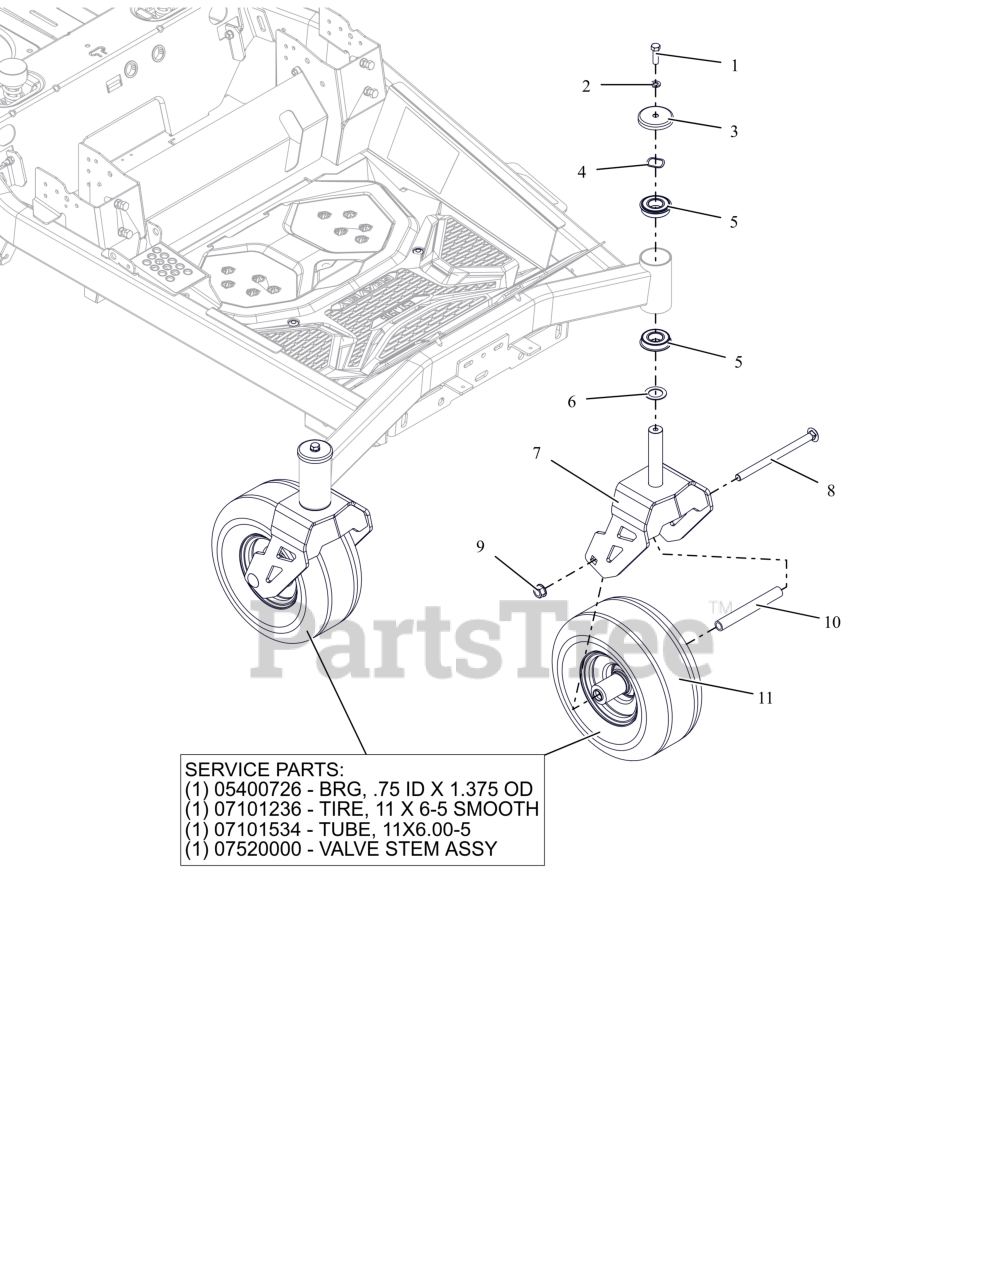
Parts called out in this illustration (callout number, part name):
1	BLT- HEX .38-16X1.25 G5 ZB500
2	WSHR-LK-REG .375X.094 ZB500
3	SHIELD- AXLE BEARING
4	WSHR-WAVE 1.0X1.25X.028 .145FH
5	BEARING, BALL -2.000 OD X 1.000 ID X .5625 W/RING
6	WSHR-HRD-THRS 1.007X1.542X.062
7	WMT-CASTER FORK-MY23-XL
8	BLT-RHSN .50-13X7.50 G5 ZCC NS
9	NUT-LK-CTR-FLG .500-13 GG ZCC
10	SPACER, FRONT WHEEL (WIDE 6.0)
11	TIRE/WHEEL ASSY 11X6-5
11	BRG, .75 ID X 1.375 OD
11	TIRE, 11X6-5 Smooth
11	VALVE STEM ASS'Y
11	Tire Tube, 11/6.0-5
